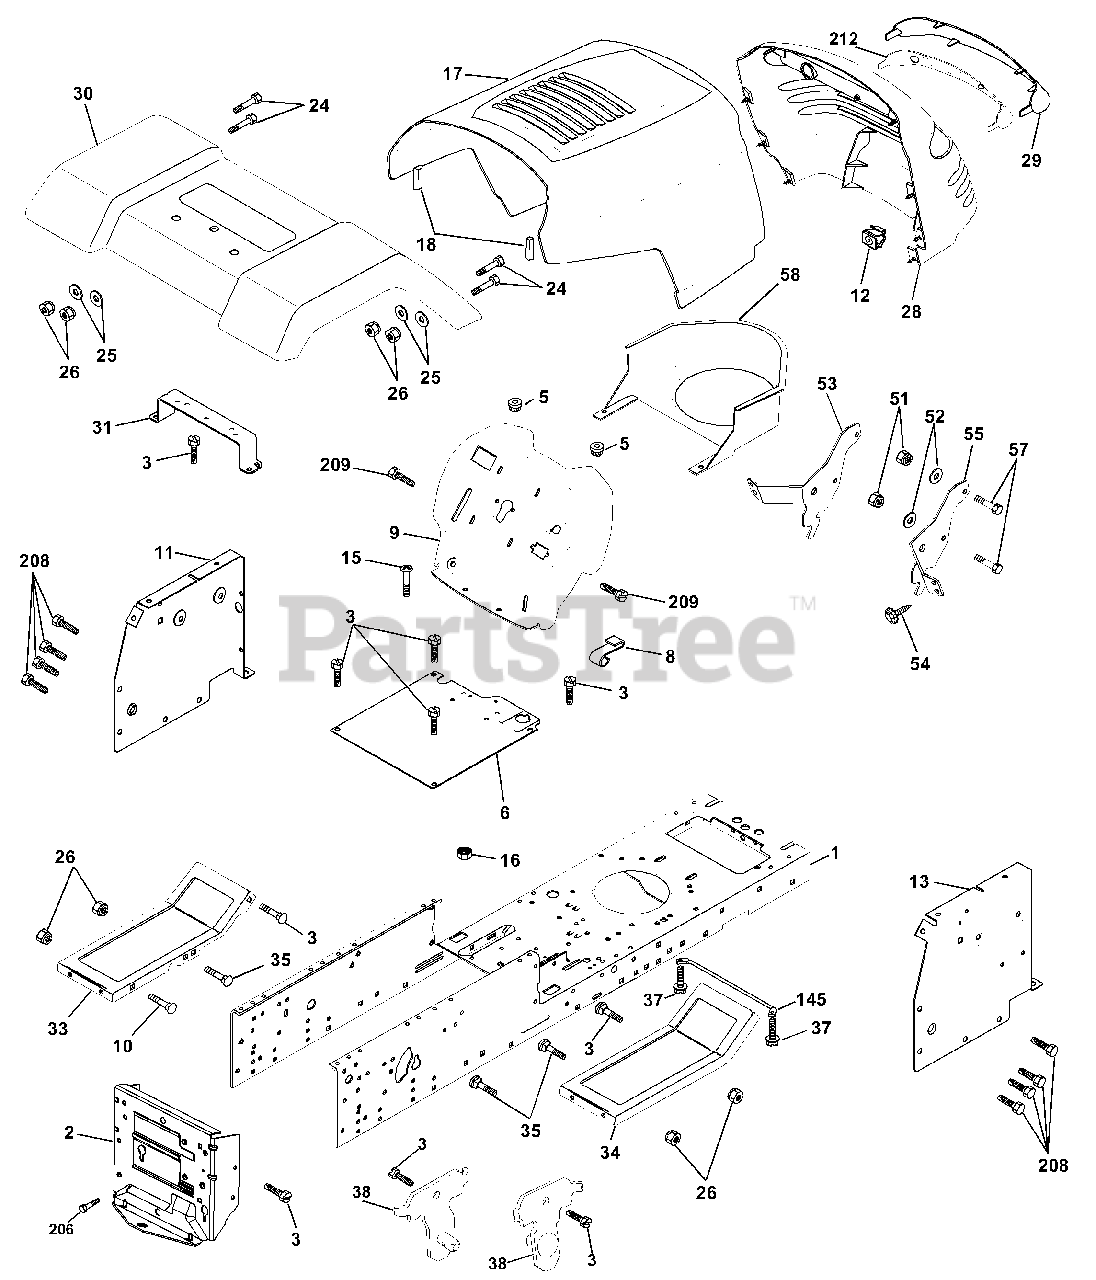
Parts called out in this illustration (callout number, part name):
1	Chassis Wldmt.
2	Drawbar Stretch 94
3	Screw Thdrol. 3/8-16 x 3/4
5	Bumper Hood/Dash
6	Saddle Flat Lt
8	Clip Retainer Slide-On
9	Dash Private Label
10	Bolt Rd Hd Sqnk. 3/8-16 Unc x 1
11	Panel Asm. Dash Lh
12	Clip Tinnerman Grille P/L
13	Panel Dash Rh
15	Screw Mach Trhd 5/16-18 Unc x 3/4
16	Nut Keps 5/16-18 Unc
17	Hood Pnt STL P/L w/trim
18	Bumper Hood
20	Plate Mtg Battery
23	Bushing Snap
24	Bolt Fin Hex 3/8-16 Unc x 1 Gr. 5
25	Washer 13/32 x 13/16 x 12 Ga.
26	Nut Lock Hex w/Insert 3/8-16 UNC
28	Grill
29	Lens Grille Private label
30	Fender Asm LT
31	Bracket Fender
33	Footrest Pnt. Lh
34	Footrest Pnt. Rh
35	Bolt Rd Hd Sht. Sqnk. 3/8-16 x 3/4
37	Screw Thdrol 5/16-18 x 1/2 Tyt
38	Bracket Asm Pivot Mower Rear
51	Nut Lock Hex W/Ins. 1/4-20
52	Washer 9/32 x 7/8 x 16 Ga.
53	Bracket Grille LH
54	Screw Hex Wshd 8-18 x 7/8
55	Bracket, Grille RH
57	Bolt Fin Hex 1/4-20 x .75
58	Air Duct
145	Rod Pivot Chassis/Hood
206	Bolt Shoulder 5/16-18
207	Screw Thdrol 5/16-18 x 1/2
208	Screw Thdrol 3/16 x 1/2
209	Screw Hexwsh Thdr 3/8-16
212	Insert Lens
